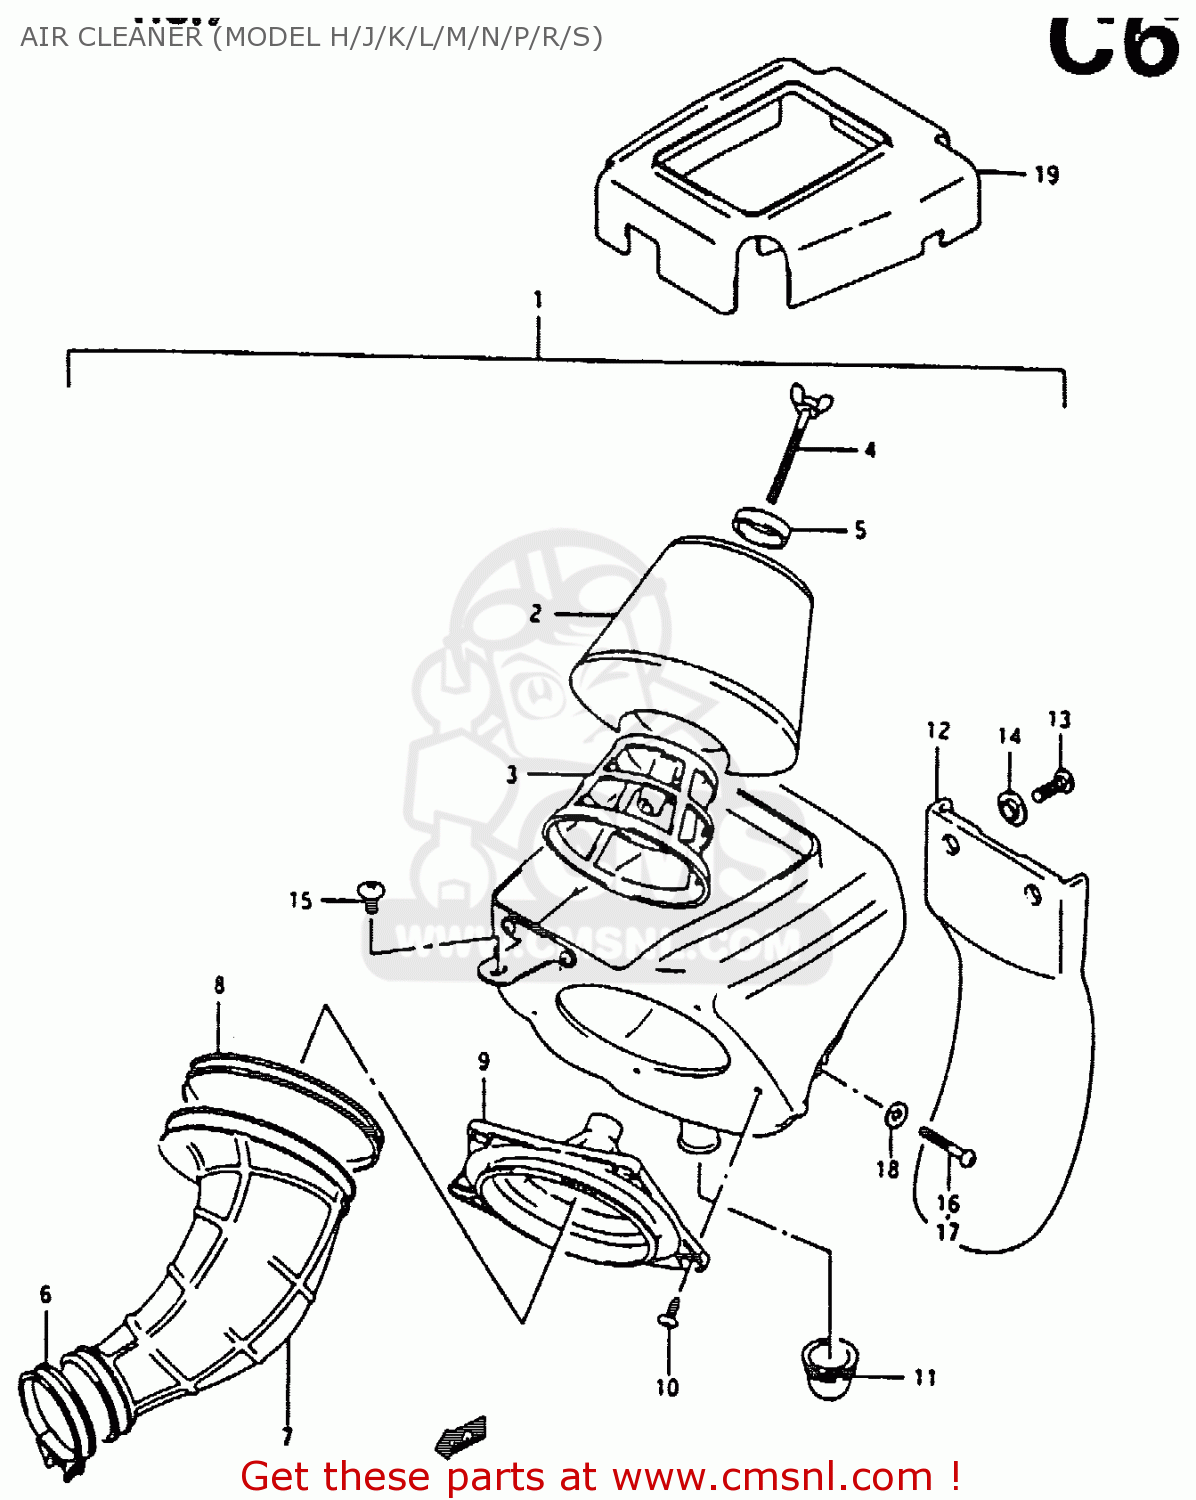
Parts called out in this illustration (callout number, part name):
1	CLEANER ASSEMBLY,AIR
2	FILTER ASSY
3	HOLDER
4	BOLT,WING
5	WASHER,AIR CLEANER
6	CLAMP
7	TUBE,AIR CLEANER OUTLET
8	CLAMP
9	BASE,FILTER
10	SCREW
11	HOSE,AIR CLEANER DRAIN
12	GUARD,MUD
13	SCREW
14	COLLAR
15	SCREW 6X12
16	SCREW
17	BOLT
18	WASHER
19	MUD GUARD,B
